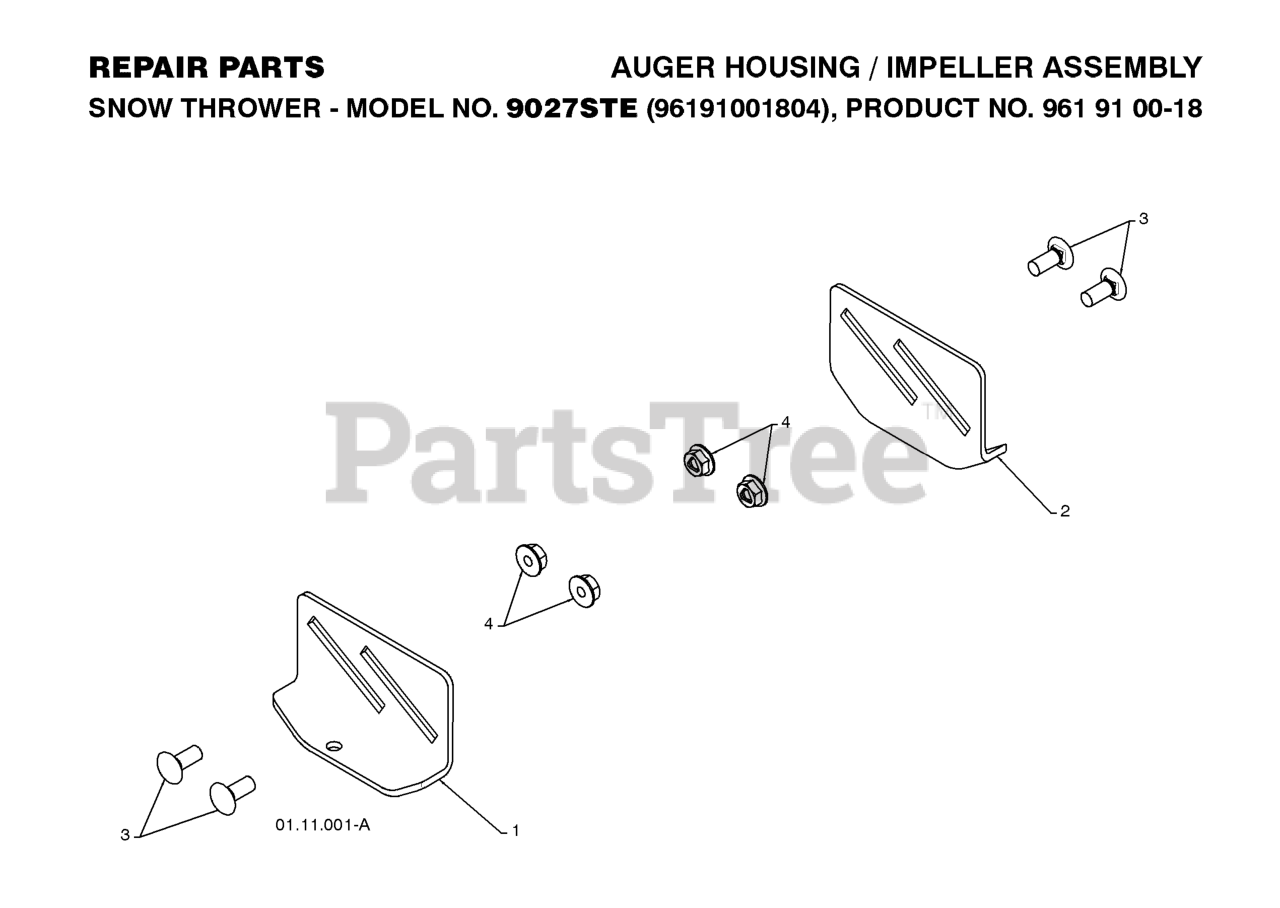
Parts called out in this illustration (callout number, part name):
1	SKID PLATE LH
2	SKID PLATE RH
3	BOLT
4	NUT.LOCK.5/16-18
